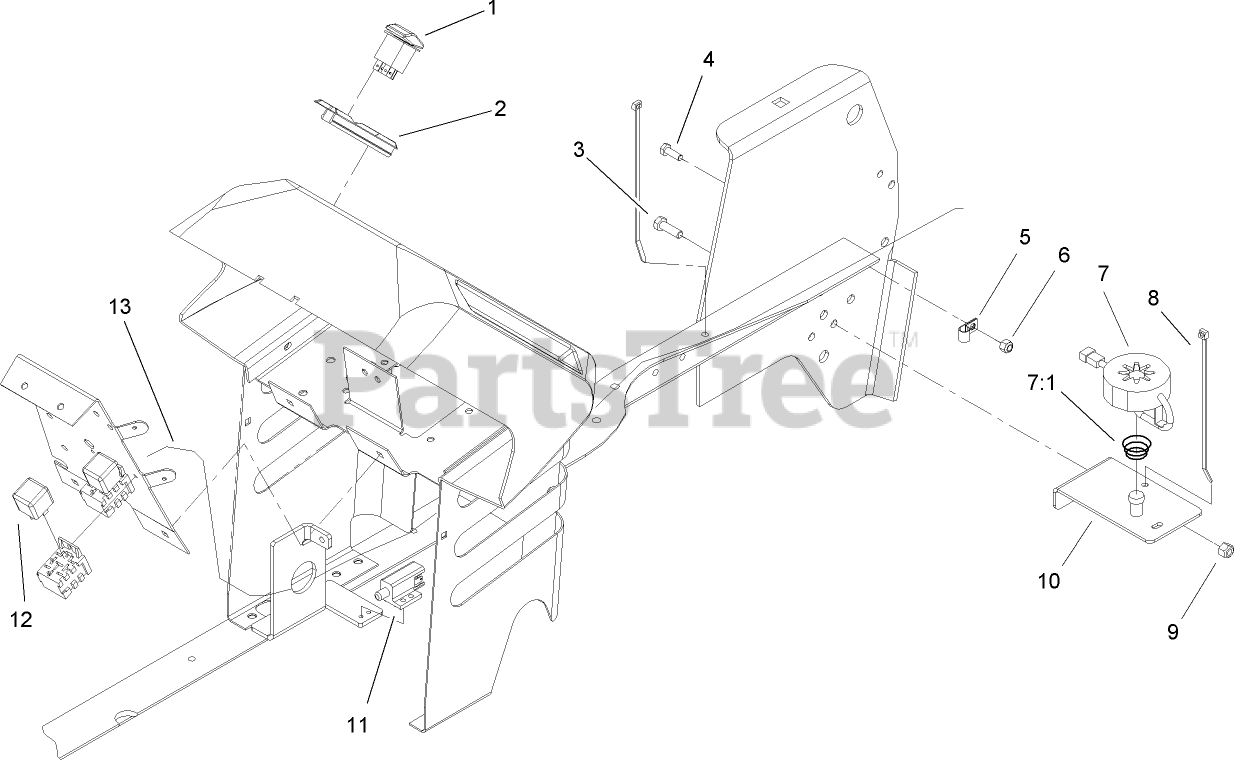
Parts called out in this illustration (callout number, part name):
1	SWITCH-CRUISE
2	COVER-SLOT, RH
3	SCREW-HH
4	SCREW-HH
5	CLAMP-R
6	NUT-LOCK, NI
7:1	SPRING-COMPRESSION
8	TIE-CABLE
9	NUT-LOCK, NI
10	BRACKET-CRUISE
12	RELAY
13	HARNESS - WIRE, CRUISE KIT
